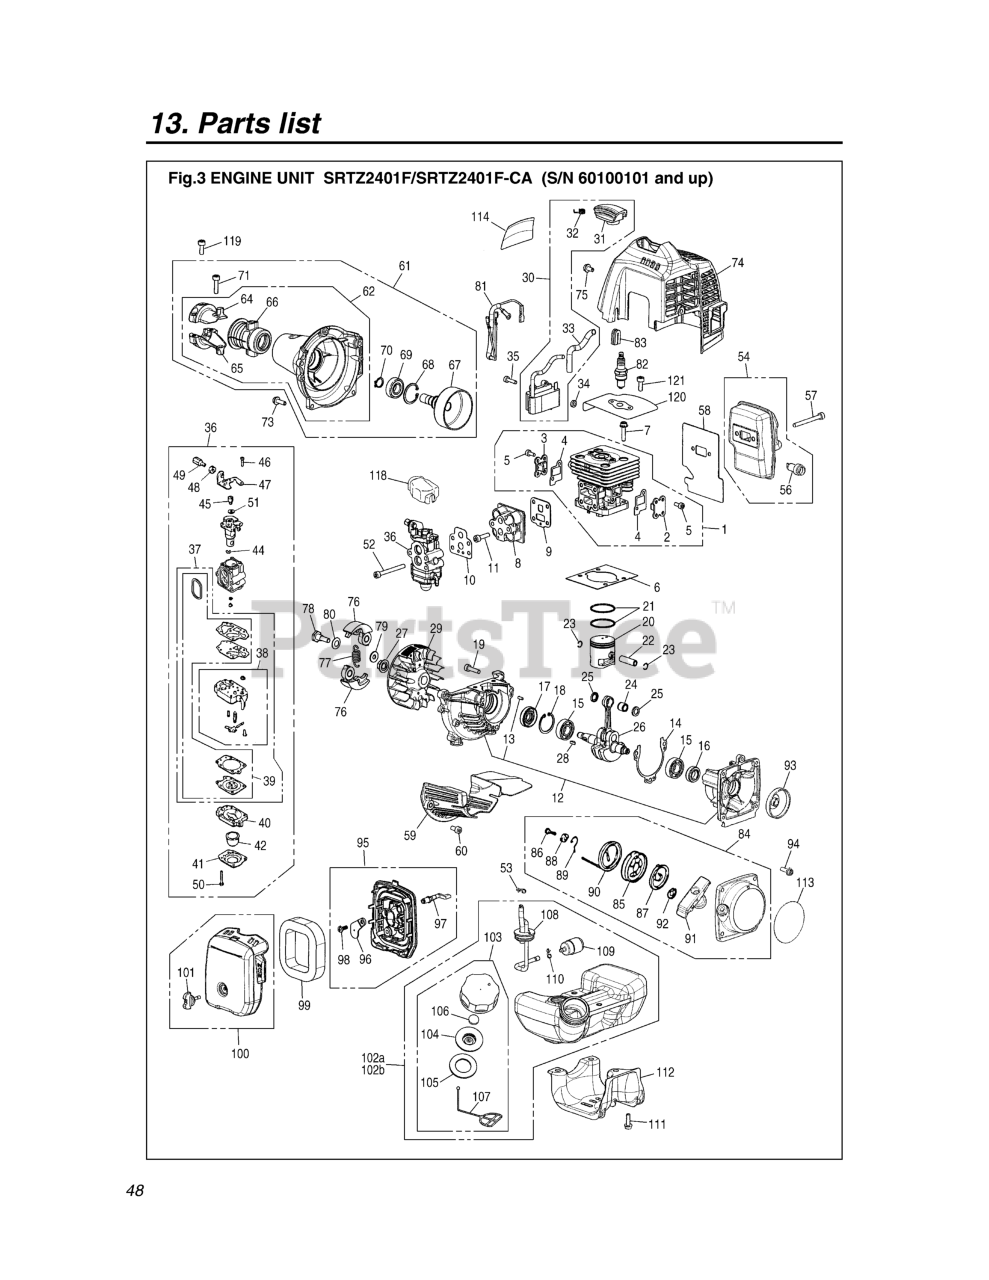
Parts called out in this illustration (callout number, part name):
1	CYLINDER-C
2	COVER, TR-S
3	COVER, TR-F
4	GASKET, TR
5	BOLT, TORX
6	GASKET, BASE
7	BOLT
8	INSULATOR
9	GASKET
10	GASKET, CARB
11	BOLT, TORX
12	CRANKCASE-C
13	PIN
14	GASKET, CASE
15	BEARING
16	SEAL
17	SEAL, OIL (RPLS 1140-21220)
18	RING, SNAP, M28 x 1.2
19	BOLT (RPLS 2850-14220)
20	PISTON
21	RING, PISTON
22	PIN, PISTON
23	RING, SNAP (RPLS 1101-41320)
24	BEARING
25	WASHER
26	CRANKSHAFT-C
28	KEY
29	ROTOR
30	COIL ASSY
31	CAP (RPLS 4810-72110)
32	SPRING
33	TUBE
34	SPACER (RPLS -71260)
35	BOLT TORX
36	CARBURETOR ASSY
37	REBUILD KIT
38	BODY, PUMP
39	KIT, GASKET (REPLACES-06020)
40	BODY, PURGE
41	COVER, PUMP
42	PUMP, PRIMING
44	RING
45	SWIVEL
46	SCREW
48	NUT
49	SCREW, CABLE ADJUSTER
50	SCREW
51	WASHER
52	BOLT
53	CLIP
54	MUFFLER-A
56	ARRESTER
57	BOLT
58	GASKET, MUFFLER
59	PLATE
60	BOLT
61	HOUSING ASSY (RPLS T1551-31000
62	HOUSING COMP (RPLS. -31110)
64	BRACKET (A) (RPLS -31211)
65	BRACKET (B)
66	CUSHION (RPLS -31231)
67	DRUM (REPLACES 4810-31122)
68	RING, SNAP, M28 x 1.2
69	BEARING
70	RING, SNAP (RPLS 3130-13270)
71	BOLT (RPLS 2850-14220)
73	BOLT
74	COVER, ENGINE
75	BOLT (RPLS. T4950-51011)
76	SHOE
77	SPRING
78	BOLT
79	WASHER, FLAT (USE 182303)
80	WASHER (RPLS -51241)
81	CORD COMP.
83	GROMMET
84	RECOIL-A
85	REEL
86	SCREW
87	SPRING, SPIRAL
88	COLLAR
89	ARM
90	ROPE (REPLACES 4500-75160)
91	KNOB (RPLS -75420)
92	PLATE, STOPPER
93	PULLEY
94	BOLT, TORX
95	BODY ASSY (RPLS T1551-82100)
96	PLATE, CHOKE
97	LEVER
98	SCREW
99	ELEMENT
100	COVER-A (RPLS T1551-82200)
101	KNOB
103	CAP ASSY (RPLS -85201)
104	HOLDER (REPLACES -85230)
105	PACKING
106	FILTER
107	STOPPER
109	FILTER ASSY
110	CLIP (REPLACES 2841-31280)
111	BOLT
112	GUARD, TANK
113	LABEL, RECOIL
114	LABEL, COVER
118	COVER
119	BOLT
120	PLATE
121	BOLT
